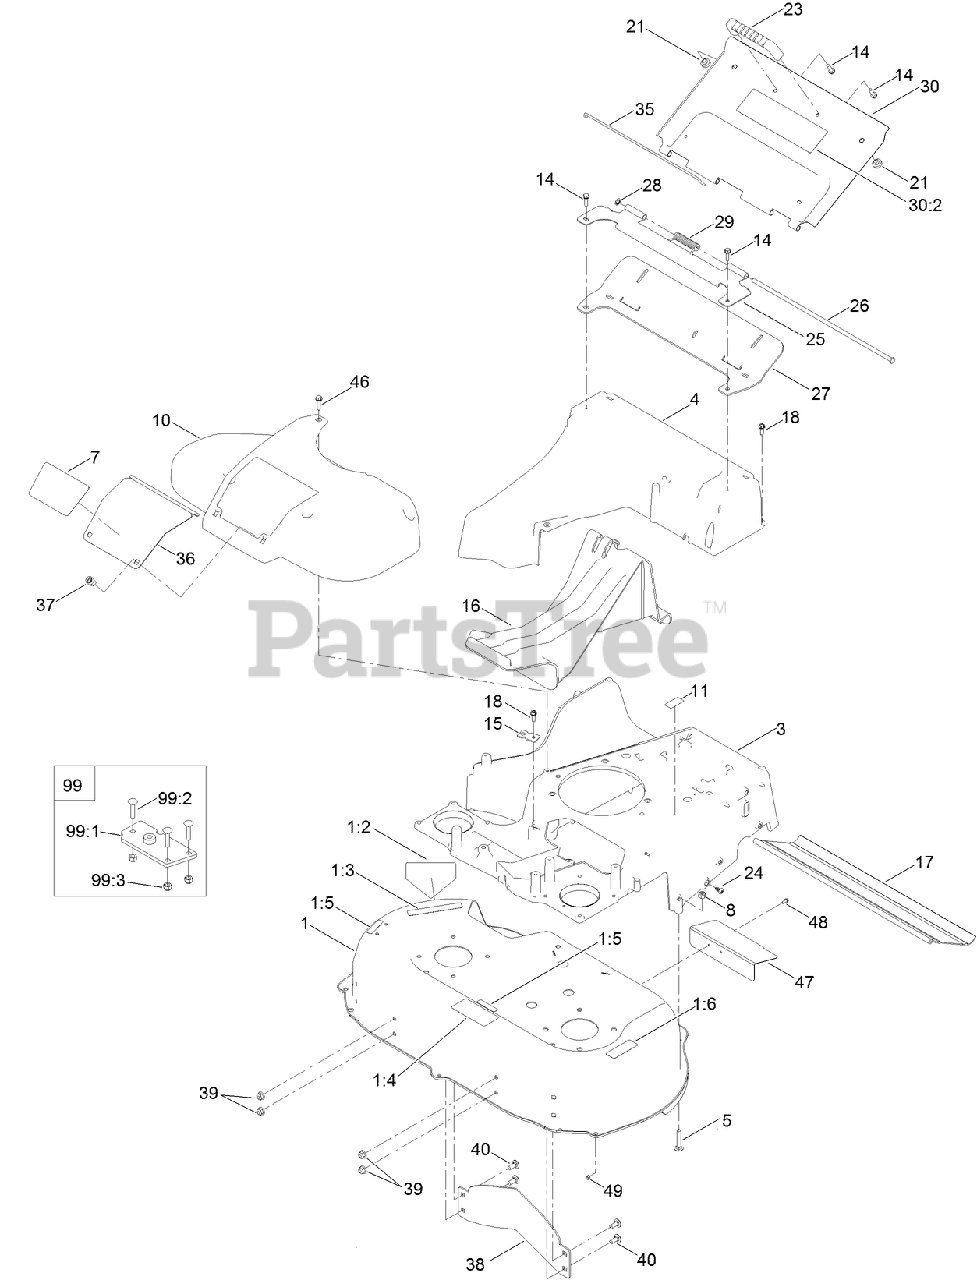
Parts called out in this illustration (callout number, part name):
1	DECK ASM
1:2	DECAL-DANGER
1:3	DECAL-DANGER
1:5	DECAL-WARNING
1:6	DECAL-WARNING, BLOCK
3	FRAME
5	BOLT-CAR
8	NUT-LOCK, NI
10	COVER-BELT
11	DECAL-PATENT
14	SCREW-HWH
15	BRACKET-CABLE, TRACTION
16	PLUG-MULCH
17	SHIELD-TRAILING
18	SCREW-HWHTF
21	BUMPER
23	HANDLE-DOOR
24	SCREW-PTH
25	BRACKET-HINGE
26	PIN-HINGE
27	SEAL-DOOR
28	RING-RETAINING
29	SPRING-TORSION, COVER
30	REAR DOOR ASM
30:2	DECAL-WARNING
35	CLIP-SEAL
36	DOOR-ACCESS
37	FASTENER
38	BAFFLE-CONTROL
39	NUT-HF, NI
40	SCREW-CARR
46	SCREW-HWHTF
47	DEFLECTOR-REAR
48	SCREW-HWH
49	NUT-LOCK, NI
99	FRAME PLATE KIT
99:1	PLATE-FRAME
99:2	SCREW-CARR
99:3	NUT-LOCK, NI
